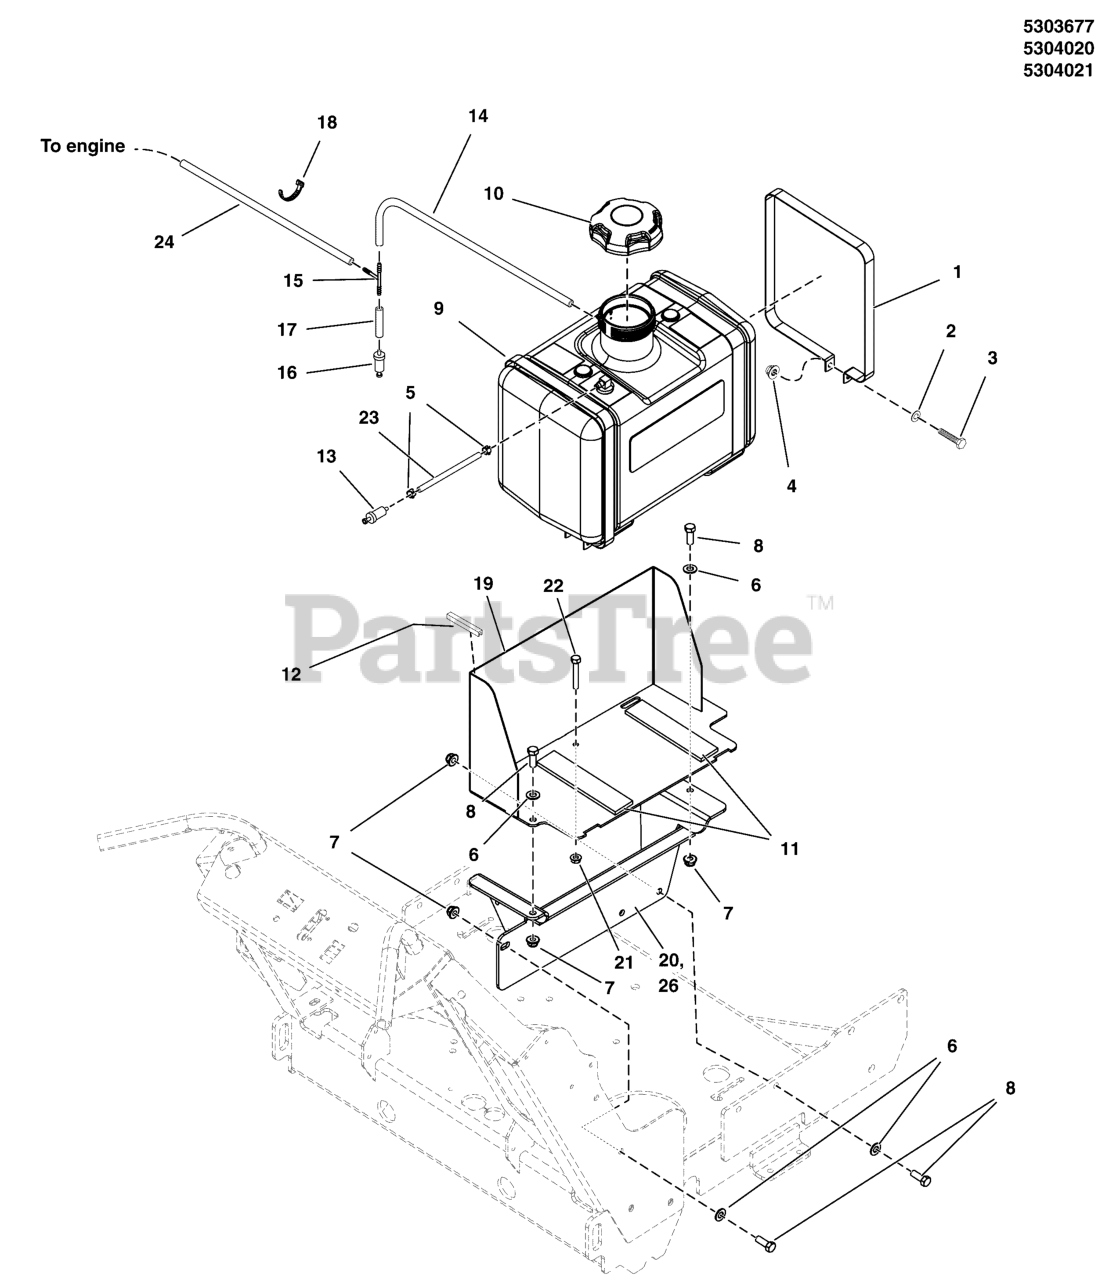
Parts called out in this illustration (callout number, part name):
1	STRAP, FUEL TANK
2	WASHER, 1/4 SAE
3	BOLT, 1/4-20 X 1-1/4, GD5
4	NUT, 1/4-20 HEX NYLOCK FLANGE
5	CLAMP, HOSE, EXTERNAL, 1/2 - RED
6	WASHER, 3/8 SAE
7	NUT, 3/8-16 HEX NYLOCK FLANGE
8	BOLT, 3/8-16 X 1" GD5 CZ
9	TANK, 5 GAL, W DROP TUBE/VENT
10	FUEL CAP, 3-1/2", MANAGED VENT OUT, 12"
11	PAD, RUBBER MOUNT
12	BODY MOLDING, 1.25" LONG
13	FUEL FILTER
14	HOSE, VAPOR, 5MM ID, 15.50 LG
15	FITTING, 3/16" TEE, BARB TYPE, HDPE
16	FILTER, FUEL
17	HOSE, VAPOR, 5MM ID, 4.50 LG
18	TIE,SELF-LOCKING, 6"
19	WELD, FUEL TANK MOUNT UPPER, W35 - BLK
20	WELD, FUEL TANK MOUNT LOWER, W35 - BLK
21	NUT, 5/16-18 HEX SERRATED FLANGE (SMALL)
22	BOLT, 5/16-18 X 2 ALL THD
23	HOSE, 1/4" FUEL, 29.50"
24	HOSE, VAPOR, 5MMID, 20.50 LG
25	GROMMET
26	WELD, FUEL TANK, MOUNT, LOWER, W35 - BLK
